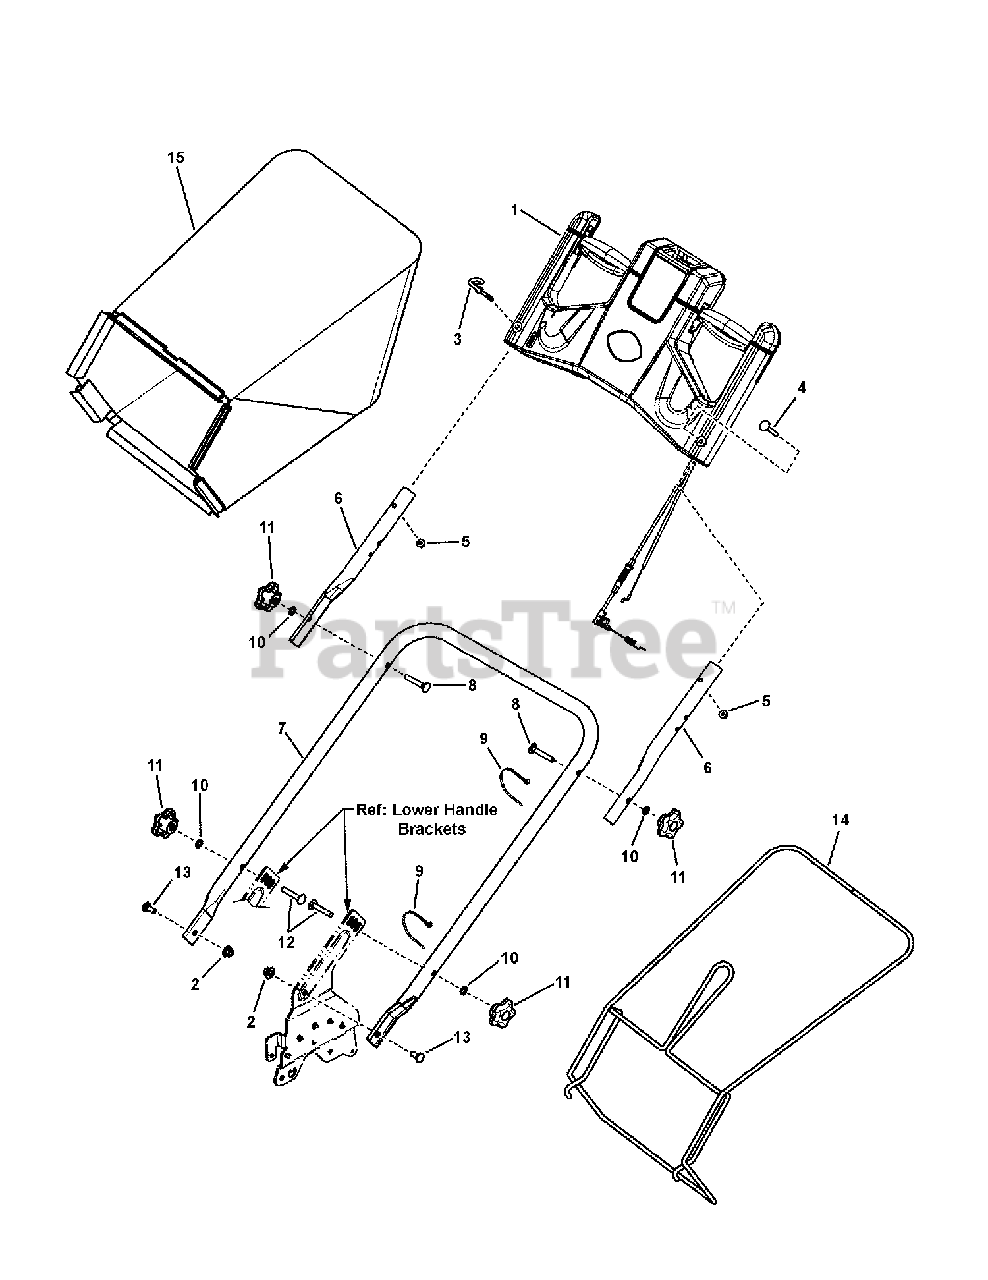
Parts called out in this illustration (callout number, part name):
1	ASSEMBLY, React Control, Front Wheel Drive
2	NUT, 5/16-18 Large Flange Center Lock
3	ROPE GUIDE, (1/4-20 thread)
4	BOLT, 1/4-20 x 1-3/4" Round Head Square Neck Carriage, GR 2, YZ
5	NUT, 1/4-20 Hex Flange (Esna), YZ
6	HANDLE, Connecting, 21"/ 22" WBM
7	HANDLE, Lower
8	BOLT, 5/16-18 x 2" Curved Head Square Neck, GR 2
9	WIRE TIE, 11 Inch Standard Black Nylon
10	WASHER, 5/16" Internal Tooth Lock
11	KNOB, Handle, 5-Prong (5/16-18 internal threads)
12	BOLT, 5/16-18 x 1-3/4" Round Head Square Neck Carriage
13	BOLT, 5/16-18 x 3/4" Round Head Short Square Neck Carriage, GR 5
14	BAG FRAME, Rear Discharge (weldment)
15	GRASS BAG, 22" Rear Discharge
